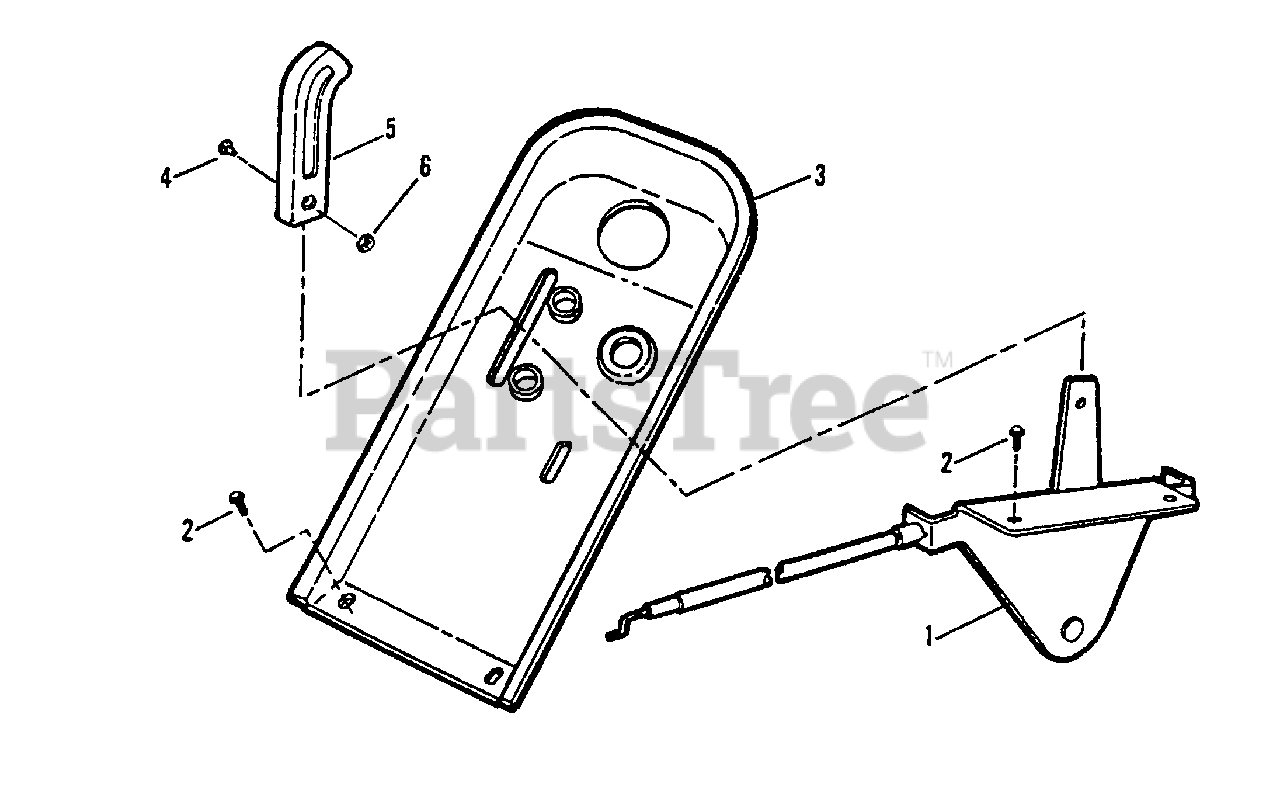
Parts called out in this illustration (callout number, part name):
1	CONTROL, Throttle 44.1" Conduit
1	CONTROL, Throttle 48.6" Conduit
2	SCREW, #10-24 x 1/2" Hex Washer Self-Tap (Torx)
3	COVER, Dash Panel (Electric Start)
4	SCREW, #8-32 x 3/8" Cross Recessed Fillister Head
5	KNOB, Throttle Control
6	NUT, #8-32 Hex, Grade 2 or B
